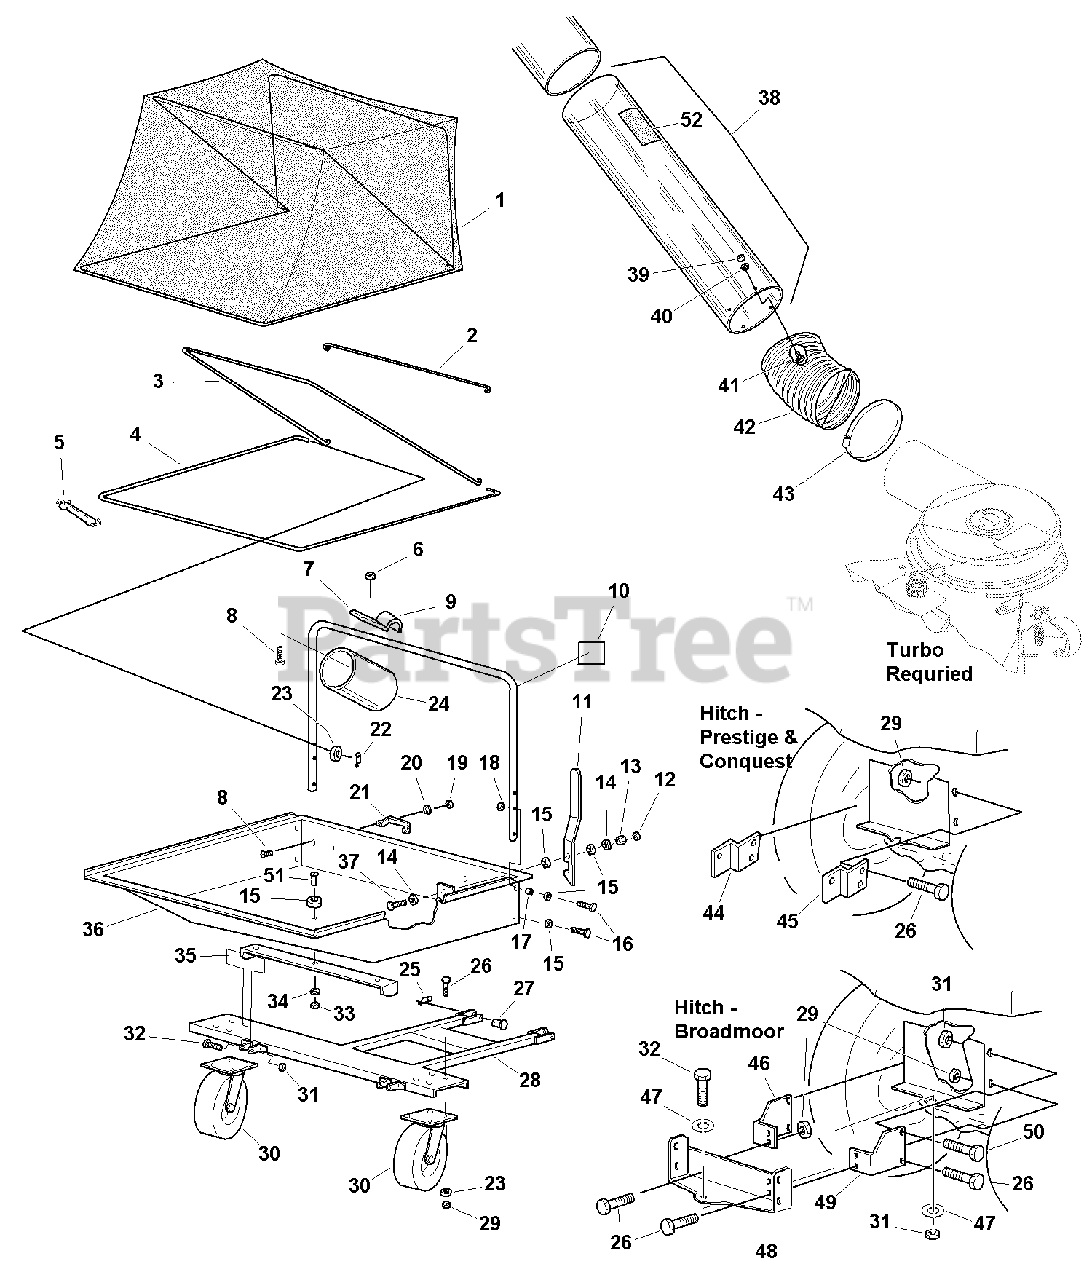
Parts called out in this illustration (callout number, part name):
1	COVER, Jrco, Cart
3	ROD, Support
5	STRAP, Rubber
6	NUT, Hex Nylock, 1/4-20
7	SLEEVE, Clamp
8	CAPSCREW, Hex Head, 1/4-20 X 1/2
9	TUBE, Support
10	DECAL, Maximum Capacity
11	HANDLE, Latch
12	NUT, Hex Jam, 5/16-18
13	NUT,Hex, 5/16-18
14	WASHER, Compression
15	WASHER, 5/16
16	CAPSCREW, Hex Head, 5/16-18 X 1-1/2
18	NUT, Hex Centerlock, 5/16-18
19	NUT, Hex, 1/4-20
20	LOCKWASHER, 1/4
21	HANDLE, Lift
22	COTTER, Circle
23	WASHER, 3/8
25	SAFETY, Pin
26	CAPSCREW, Hex Head, 3/8-16 X 1
27	PIN, Rnd, Head, Drilled, 1/2 X 1-1/2
28	FRAME ASSEMBLY
29	NUT, Hex Centerlock, 3/8-16
30	WHEEL Assembly, Swivel
31	NUT, Hex Centerlock, 1/2-13
32	CAPSCREW, Hex Head, 1/2-13 X 1-1/4
33	NUT, Hex, 5/16
34	LOCKWASHER, 5/16
35	BRACKET, "U"
36	BOX, Jrco 44"
37	CAPSCREW, Hex Head, 5/16-18 X 1-1/4
38	TUBE & DECAL ASSEMBLY (Includes Ref. No.52)
39	NUT, Hex Washer Assembly, #10-32
40	WASHER, #10-32
41	SCREW, Truss Head Phillips, #10-32 x 1/2
42	HOSE, Vac Col, 6 X 12
43	CLAMP, Hose 6", Band Type
44	BRACKET, LH
45	BRACKET, RH
46	ADAPTER, Hitch LH
47	WASHER, 1/2
48	HITCH, Jarco Cart
49	ADAPTER, Hitch RH
50	CAPSCREW, Hex Head, 1/2-13 x 1
51	SCREW, Truss Head Slotted, 5/16-18 x 3/4
52	DECAL, Cleaning Instructions
